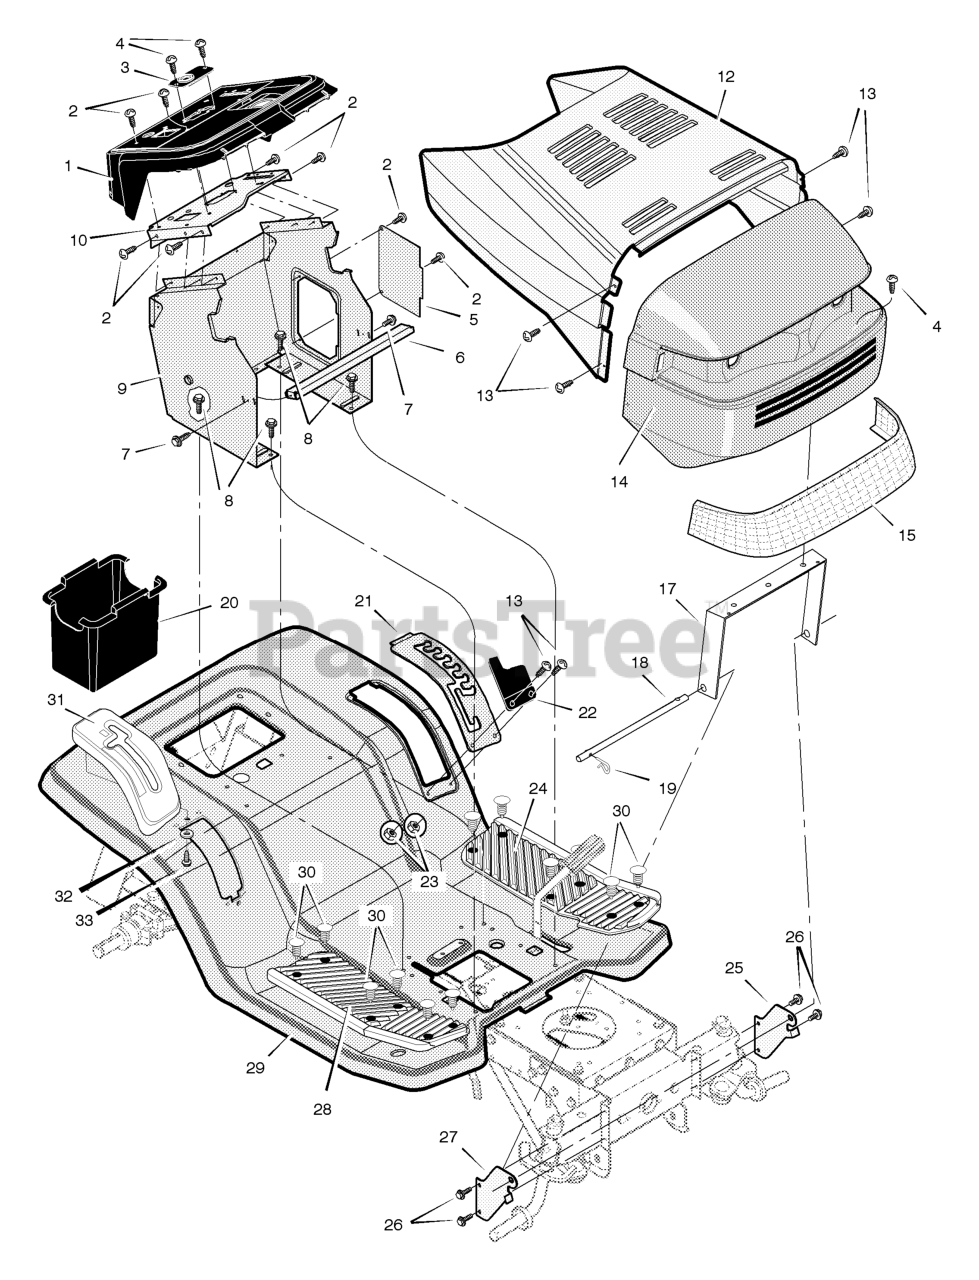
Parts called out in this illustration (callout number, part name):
2	Screw
3	Bearing, Upper Steering
5	Panel, Side Access
6	Channel, Support
9	Support, Dash
10	Plate, Dash
12	Hood
13	Bolt, Shoulder
14	Grille
15	Lens, Right
17	Brace, Grille
18	Rod, Pivot
19	Pin, Hair
20	Container, Battery
21	Plate, Lift Detent
24	Mat, Left
25	Support, Left Grille
27	Support, Right Grille
28	Mat, Right
29	Deck, Seat
30	Fastener, Panel
31	Cover, Shift
